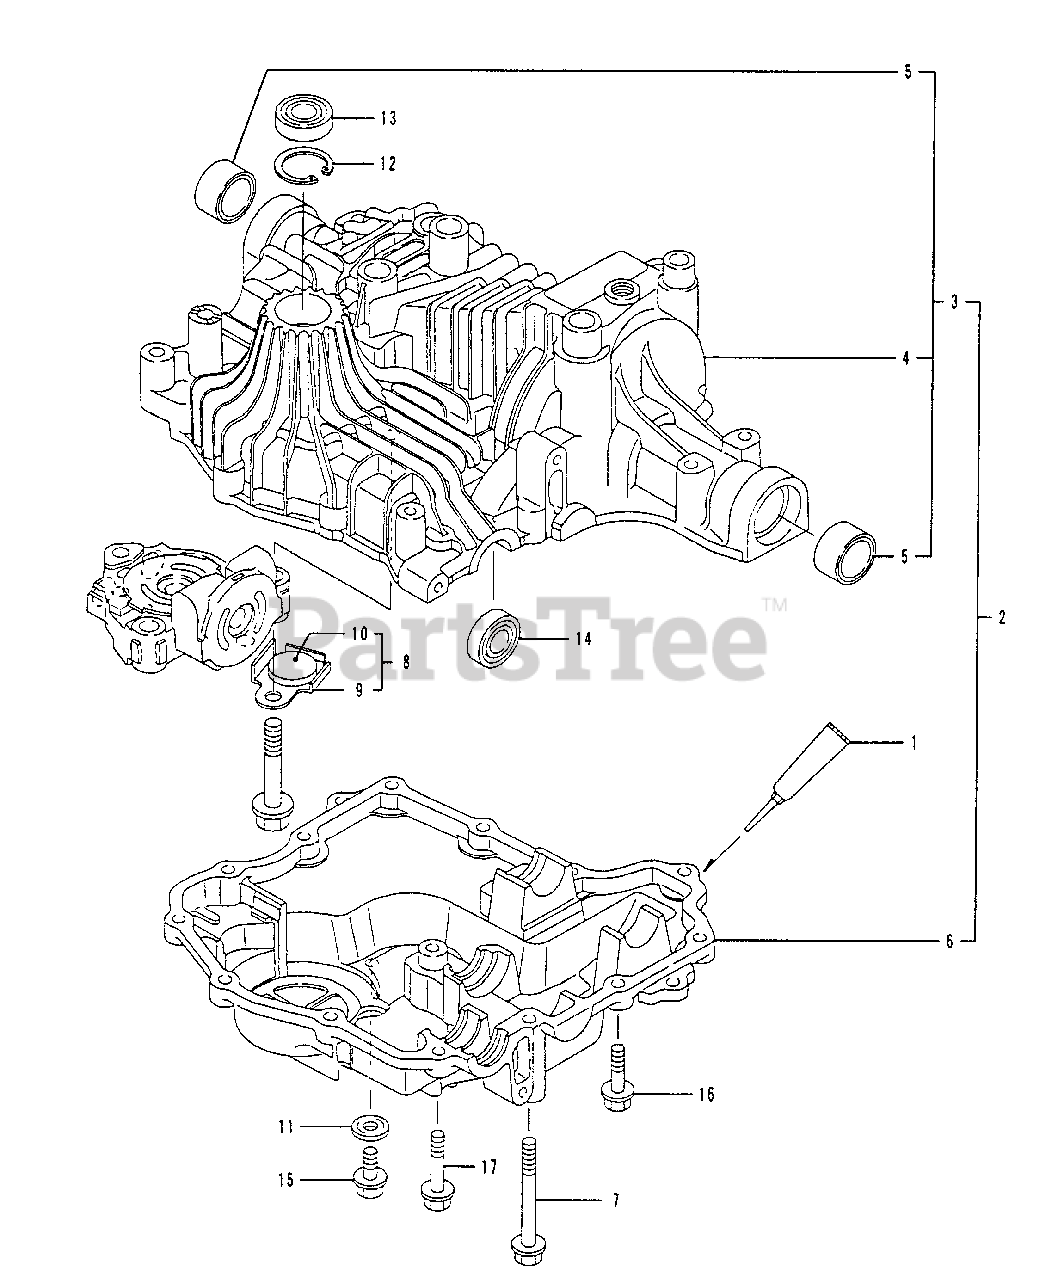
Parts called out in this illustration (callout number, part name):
2	TRANSAXLE CASE SET
3	UPPER CASE COMP.
4	UPPER CASE
5	BUSHING 25.4
7	BOLT 8 X 75
8	MAGNET, CMP
9	HOLDER, MAGNET
10	MAGNET. 30 X 5
11	WASHER, SEAL 8
13	SEAL TC153507
14	SEAL TC173507
15	BOLT 8 X 12
16	TAPPING, SCREW 8 x 30
17	TAPPING, SCREW 8 X 40
